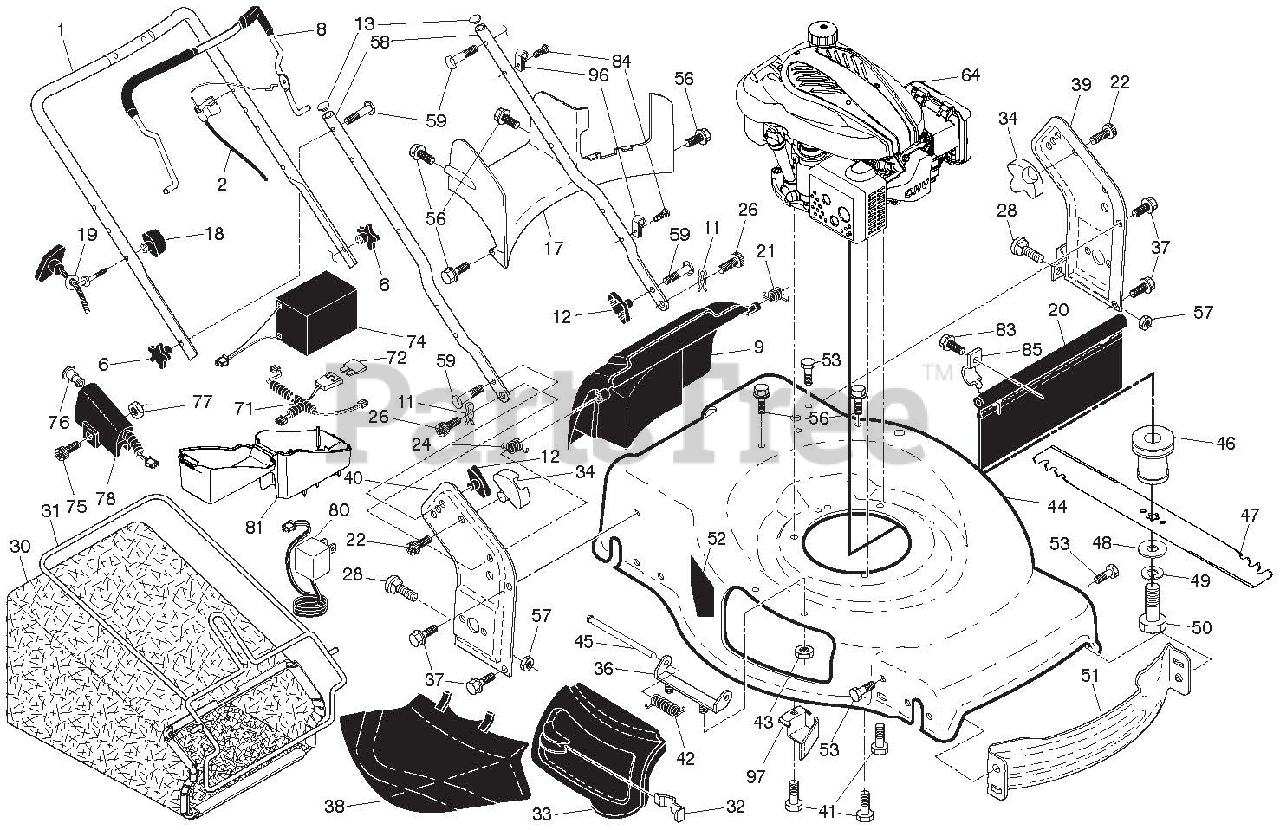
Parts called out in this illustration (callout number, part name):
1	UPPER HANDLE ASSEMBLY
2	CABLE, ENGINE ZONE CONTROL
6	Handle Knob
8	CONTROL BAR
9	REAR DOOR ASSEMBLY
11	HAIRPIN, DOOR/HANDLE PIVOT
12	HANDLE KNOB, STANDARD
13	PLUG, HANDLE BAR
17	REAR BAFFLE
19	ROPE GUIDE
20	REAR SKIRT
21	SPRING, REAR DOOR, LH, BLACK
22	SCREW, PANHEAD, TORX #20
24	SPRING, REAR DOOR, RH, GREY
26	SCREW, REAR DOOR/HANDLE PIVOT
28	BOLT, CARRIAGE
30	GRASSBAG
31	FRAME, GRASSBAG
32	LATCH, MULCHER DOOR
33	MULCHER DOOR
34	BRACKET, GRASSBAG
36	Hinge Bracket Assembly
37	BOLT.5/16-18HEX.WHS.HD.LCKSERR
38	DISCHARGE DEFLECTOR
39	HANDLE BRACKET, LH
40	HANDLE BRACKET, RH
41	Screw, Hex Head, Threaded, Rol
42	Spring, Torsion
43	LOCKNUT, HEX 1/4-20
44	KIT, LAWN MOWER HOUSING
45	Rod, Hinge
46	BLADE ADAPTER
47	BLADE 22"
48	Hardened Washer
49	Helical Lockwasher
50	Screw, Hex Head, Grade 8 3/8-2
51	FRONT BAFFLE
52	DECAL, WARNING
53	BOLT.5/16-18HEX.WHS.HD.LCKSERR
56	Screw, Rear Baffle
57	NUT, HEX
58	BAR, LOWER HANDLE
59	Handle Bolt
64	ENGINE,LNCN T322002897-2172008
71	HARNESS, WIRING
72	FUSE, 40 AMP
74	BATTERY
78	ELECT START (W/SWITCH & HSNG)
80	CHARGER
81	BOX, BATTERY
84	FASTENER, PUSH
85	MOUNTING BRACKET, REAR SKIRT
96	Clip, Cable
97	BELT KEEPER
